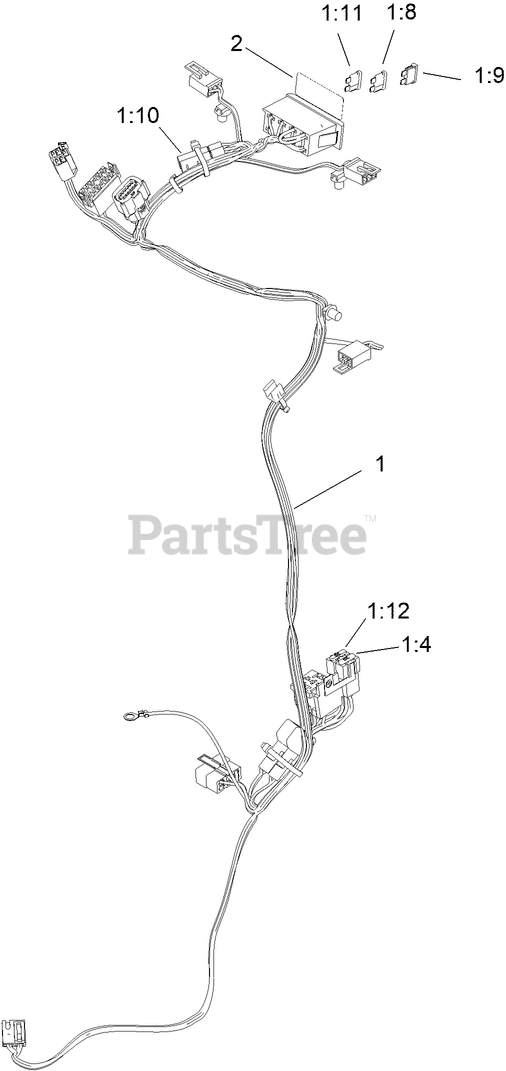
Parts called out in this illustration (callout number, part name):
1	HARNESS-WIRE, GRANDSTAND
1:4	FUSE-BLADE, 20 AMP
1:8	FUSE-BLADE, 15 AMP
1:9	FUSE-BLADE, 10 AMP
1:10	CAP-PLUG
1:11	FUSE-BLADE, 5 AMP
1:12	FUSE-BLADE, 30 AMP
2	DECAL - FUSE
